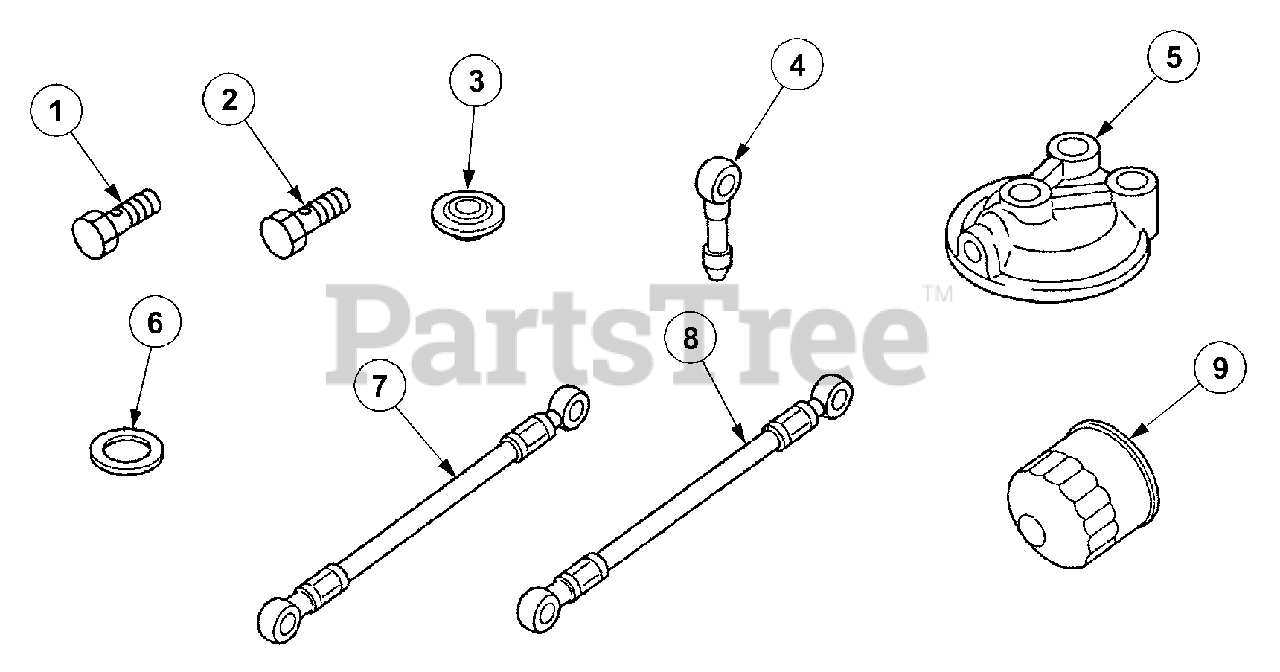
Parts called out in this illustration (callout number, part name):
3	Washer,Sealing
5	Bracket,Oil
6	Washer,Sealing
7	Tube Assy,Oil
8	Tube Assy,Oil
9	Filter Assy,Oil
